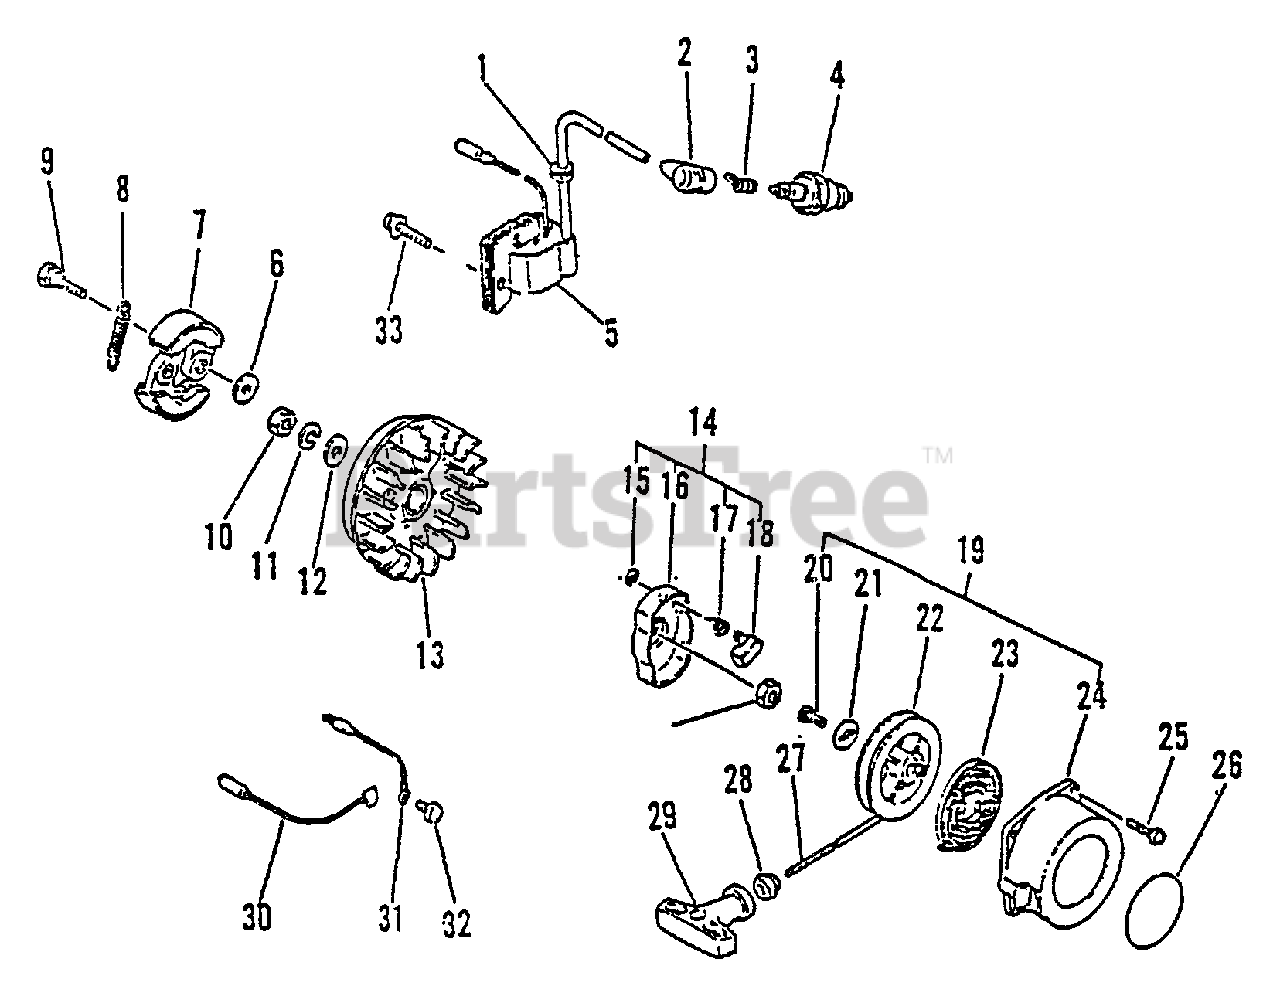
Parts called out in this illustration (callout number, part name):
2	CAP, SPARK PLUG
3	TERMINAL, SPARK PLUG
4	SPARK PLUG - BPM7A
5	COIL, IGNITION
6	WASHER 6.2×19×1.0
7	SHOE, CLUTCH
8	SPRING, CLUTCH
9	BOLT, CLUTCH
10	NUT 8×1.25
11	WASHER, SPRING 8
12	WASHER 8.5×16×1.2
13	FLYWHEEL
14	PAWL ASSY, STARTER
15	E-RING 4
16	CATCHER, PAWL
17	SPRING, RETURN
18	PAWL, STARTER
19	STARTER ASSY
21	WASHER
22	REEL, ROPE
23	SPRING, RECOIL
24	CASE, STARTER
25	SCREW 4×14
26	LABEL, ECHO
27	ROPE, STARTER 3.5×850
28	GUIDE, ROPE
29	GRIP, STARTER
30	LEAD - GROUND
31	LEAD - GROUND L= 115
32	SCREW 5×10
33	SCREW 5×28
